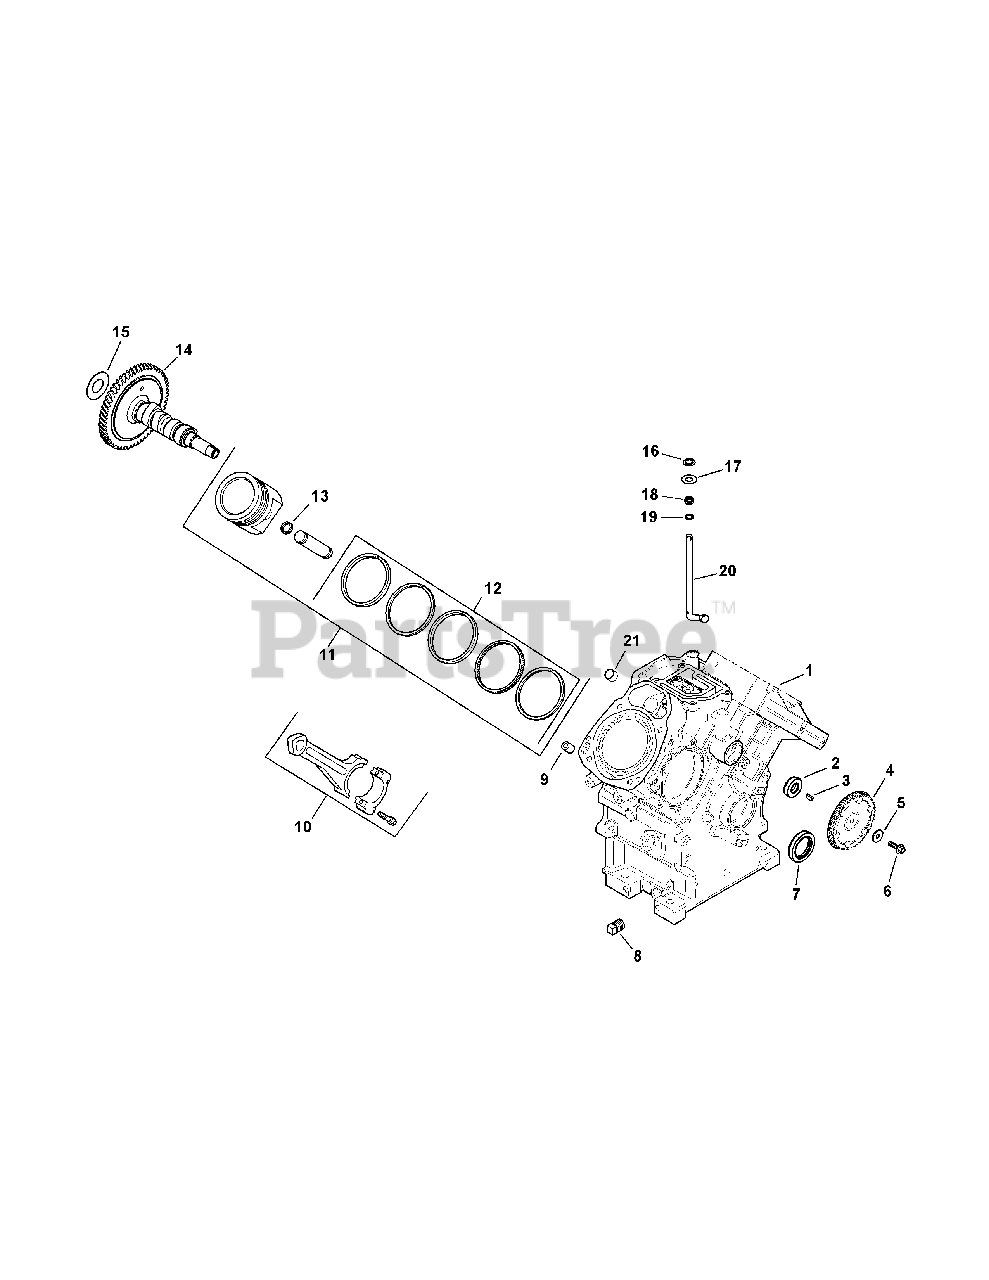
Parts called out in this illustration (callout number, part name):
1	Crankcase
2	Seal, Camshaft
3	Key, 3/32" x 3/8"
4	Sprocket, Camshaft
5	Washer, Flat 1/4"
6	Screw, Flg, M6 x 1.0 x 20
7	Seal, Oil (Helix Lip)
8	Plug, Sq Hd Pipe, 3/8"
9	Pin, Locating
10	Connecting Rod (Std)
10	Connecting Rod (.25)
11	Kit, Piston w/Ring Set (Incl.12,13)
11	Kit, Piston w/Ring Set (.08)
12	Ring Set (Std)
12	Ring Set (.08)
13	Retainer, Piston Pin
14	Kit Camshaft - EFI (Incl KH-25-357-14-S)
15	Shim, Camshaft (White .028")
15	Shim, Camshaft (Blue .03")
15	Shim, Camshaft (Red .032")
15	Shim, Camshaft (Yellow .034")
15	Shim, Camshaft (Green .036")
15	Shim, Camshaft (Gray .038")
15	Shim, Camshaft (Black .04")
16	Retainer, Ring
17	Washer, Flat 9 mm
18	Seal, Governor Cross Shaft
19	Washer, Flat, 11/32"
20	Shaft, Governor Cross
